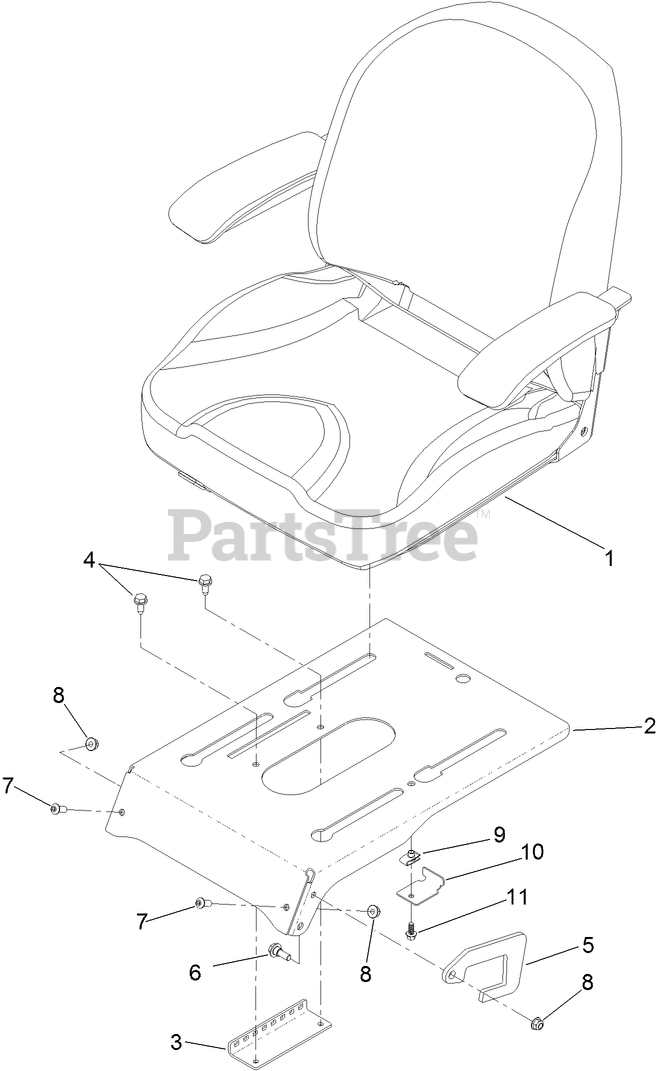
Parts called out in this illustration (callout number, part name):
1	SEAT ASM
2	PAN-SEAT
3	BRACKET-LATCH, SEAT
4	SCREW-HWHTF
5	PLATE-STOP
6	SCREW-SHOULDER
7	SCREW-HSBH
8	NUT-HF, NI
10	BRACKET-STOP, SEAT
11	SCREW-HHF
